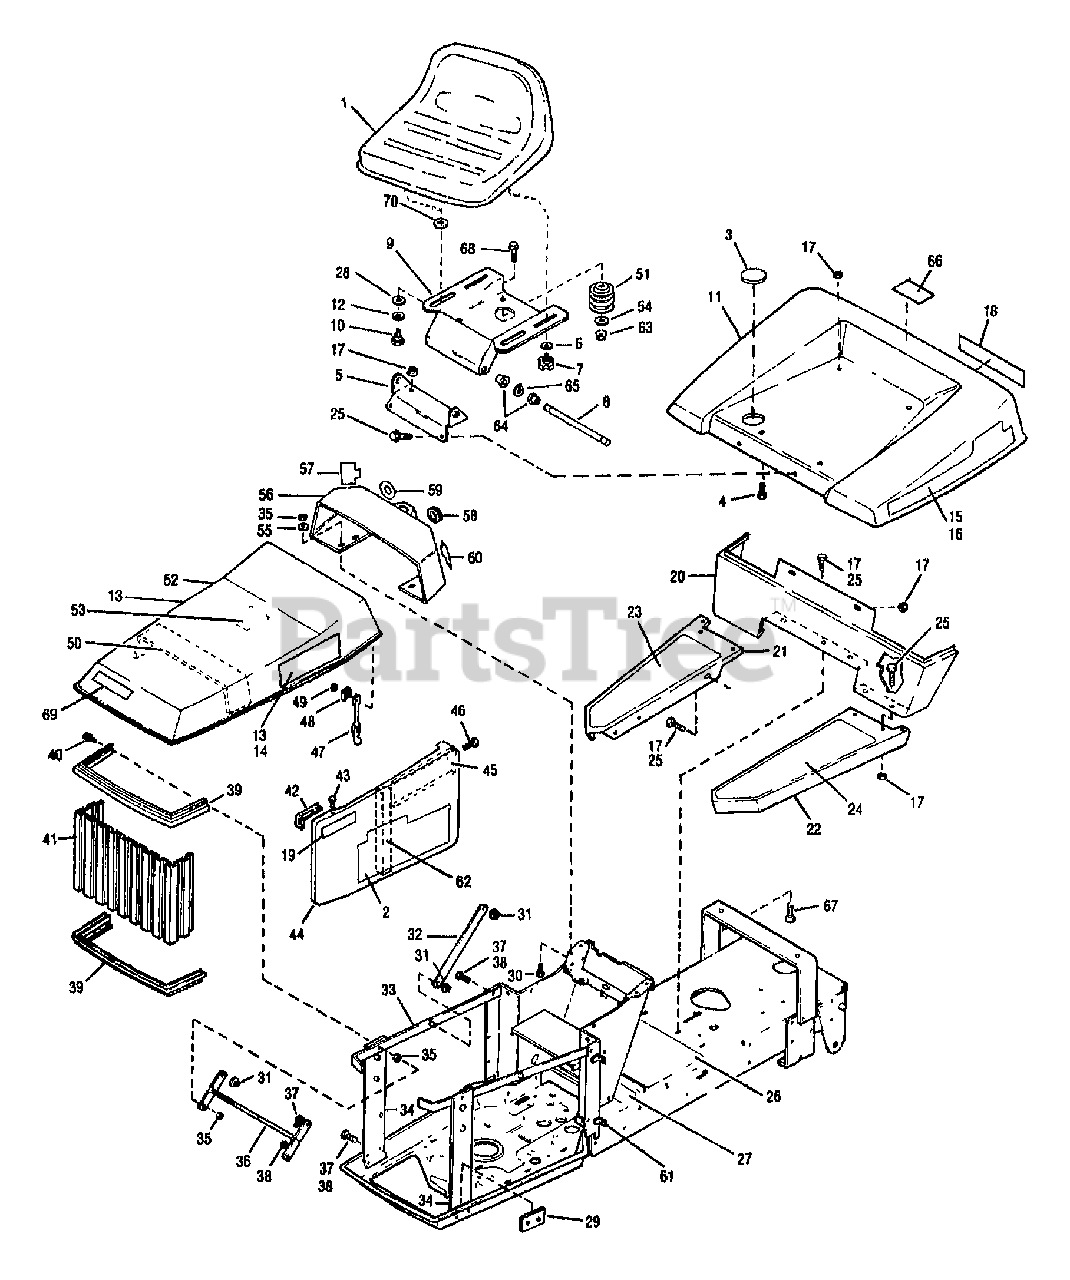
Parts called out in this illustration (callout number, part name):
1	SEAT {3214HR,3214HRS,3312HR}
1	SEAT {3312HR,3312HRS}
1	SEAT-TRACTOR {3016HR,3016HRS}
2	DECAL-SIDE COVER LH {3212HR,3114HR}
2	DECAL-SIDE COVER RH {3212HR,3114HR}
2	DECAL-SIDECVR LH RED {3312HR,3212HRS,3214HR, 3214HRS,3016HR,3016HRS}
2	DECAL-SIDECVR RH RED {3312HR,3312HRS,3214HR, 3214HRS,3016HR,3016HRS}
4	BOLT-CARR 5/16-18X.63 ZP
5	BRACKET-PIVOT
6	FLAT WASHER 3/8
9	ASSM-SEAT SUPPORT
10	SCR-SHLDR 3/8-16X.25 G5ZP
11	FENDER-REAR
12	WASHER-1.06X.51X.09 NYLON
13	DECAL-HOOD RH {3212HR,3114HR}
13	DECAL-LOGO {3214HR,3214HRS,3312HR}
13	DECAL-LOGO {3312HR,3312HRS,3016HR,3016HRS, 3214HRS}
14	DECAL-HOOD LH {3212HR,3114HR}
14	DECAL-LOGO {3312HR,3214HR}
15	DECAL-FENDER RH {3212HR}
15	DECAL-FENDER RH {3114HR}
15	DECAL-FENDER RH RED {3312HR,3312HRS}
15	DECAL-FENDER RH RED {3214HR,3214HRS}
15	DECAL-FENDER {3016HR,3016HRS}
16	DECAL-FENDER LH {3212HR}
16	DECAL-FENDER LH {3114HR}
16	DECAL-FENDER LH RED {3312HR,3312HRS}
16	DECAL-FENDER LH RED {3214HR,3214HRS}
16	DECAL-FENDER LH {3016HR,3016HRS}
17	NUT-HFLK 5/16-18 ZP
18	DECAL-LOGO {3212HR,3114HR}
18	DECAL-LOGO FENDER {3214HR,3214HRS,3312HR}
18	DECAL-LOGO FENDER {3312HR,3312HRS,3016HR, 3016HRS,3214HRS}
19	DECAL {3212HR,3114HR}
20	SUPT-RUNNING BOARD
21	BOARD-RUNNING RH
22	BOARD-RUNNING LH
23	PAD-FOOT RH {3212HR,3016HR,3016HRS,3312HR, 3312HRS}
23	PAD-FOOT RH {3114HR,3214HR,3214HRS}
24	PAD-FOOT LH
25	SCR-LOCK
26	PAD-FOOT
27	DECAL-INSTRUCTION
28	WASHER-BOW .74X.52X.01
29	SPACER-PLATE
30	HEX HD. SCREW
31	RETAINER-PUSH ON .24X.73 ZP
33	ASSM-HINGE STRAP
34	ASSM-GRILLE SUPPORT {3212HR,3114HR}
34	ASSM-GRILLE SUPT (RED)
35	NUT-HT LK 1/4-20
37	SCR-HH 1/4-20X.625
38	NUT-HF/LK 1/4-20 ZP
39	CAP-GRILLE {3212HR,3114HR}
39	CAP-GRILLE {3312HR,3312HRS,3214HR,3214HRS, 3016HR,3016HRS}
40	HEX HD. SCREW
41	GRILLE-BLACK {3212HR,3114HR}
41	GRILLE-BLACK {3312HR,3214HR}
42	GUIDE-SIDECOVER {3212HR,3114HR}
42	GUIDE-SIDE CVR (RED) {3312HR,3312HRS,3214HR, 3214HRS}
43	RIVET-POP .125 {3212HR,3114HR}
43	RIVET-POP {3312HR,3312HRS,3214HR,3214HRS}
44	COVER-SIDE LH {3212HR,3114HR}
44	COVER-SIDE LH RED {3312HR,3312HRS,3214HR, 3214HRS,3016HR,3016HRS}
44	COVER-SIDE RH {3212HR,3114HR}
44	COVER-SIDE RH RED TRACTOR {3312HR,3312HRS, 3214HR,3214HRS,3016HR,3016HRS}
45	BLOCK-SEALING {3114HR,3214HR,3214HRS,3016HR, 3016HRS}
46	SCREW
47	LATCH-RUBBER
49	NUT W/LKWASHER 10-24 ZP
50	STRIP-SEALING {3114HR,3214HR,3214HRS,3016HR, 3016HRS}
51	SPRING-COMPRESSION
52	ASSM-HOOD {3212HR,3114HR}
52	ASSM-HOOD RED {3312HR,3312HRS,3214HR, 3214HRS,3016HR,3016HRS}
53	DECAL-SVC INST
54	WASHER-FLAT 1.25X.406X.179
55	FLAT WASHER
56	PANEL-INSTRUCTION
57	DECAL-THROTTLE {3114HR,3214HR,3214HRS}
57	DECAL-THROTTLE {3212HR,3312HR,3312HRS}
59	DECAL-IGNITION
60	DECAL-CHOKE
61	NUT-SPEED
62	STRIP-SEALING {3114HR,3016HR,3016HRS,3312HR, 3214HRS}
63	NUT-HFLK 3/8-16 ZP
64	BEARING-FLANGE
65	RING-RET."E" .300 ID
66	DECAL-FUEL
67	BOLT-CARR 5/16-18X.63 ZP
68	SCR-HFLK 3/8-16X1.00 ZP
69	DECAL-MODEL {3212HR,3114HR}
69	DECAL-LOGO {3312HR,3314HR}
69	DECAL-LOGO {3312HR,3312HRS,3016HR,3016HRS, 3214HRS}
70	WASHER-FLAT
